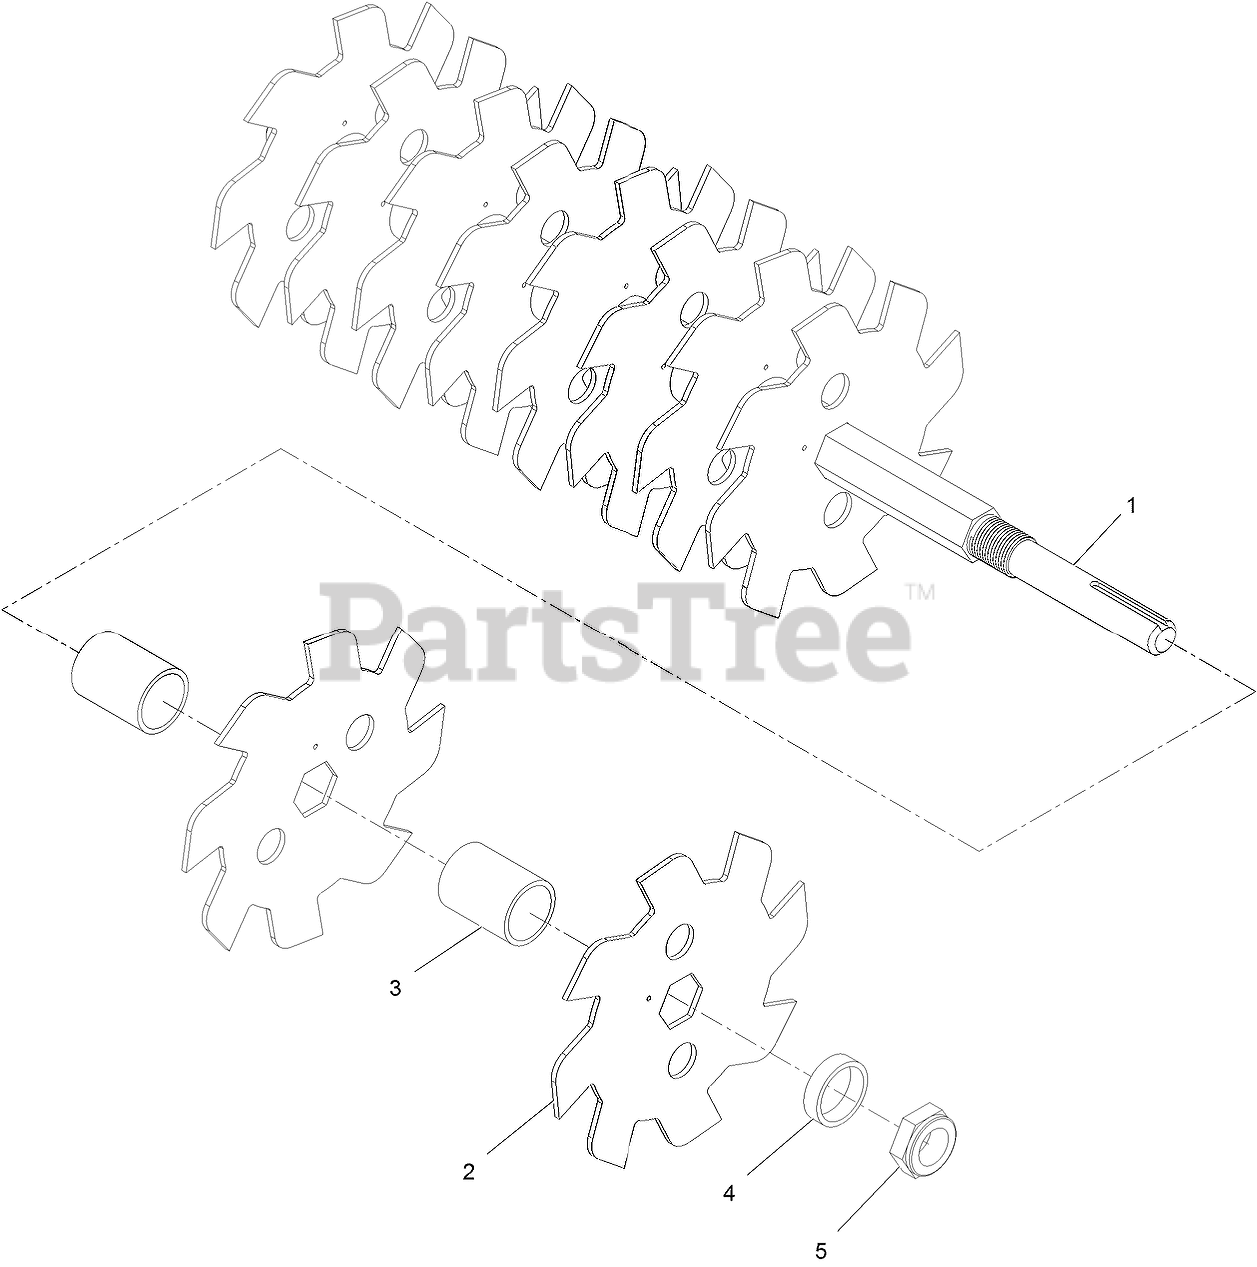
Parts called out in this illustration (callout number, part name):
1	SHAFT-SLICER
2	Blade-Cutting, Seeder
3	SPACER-BLADE
5	NUT-LOCK, NI
